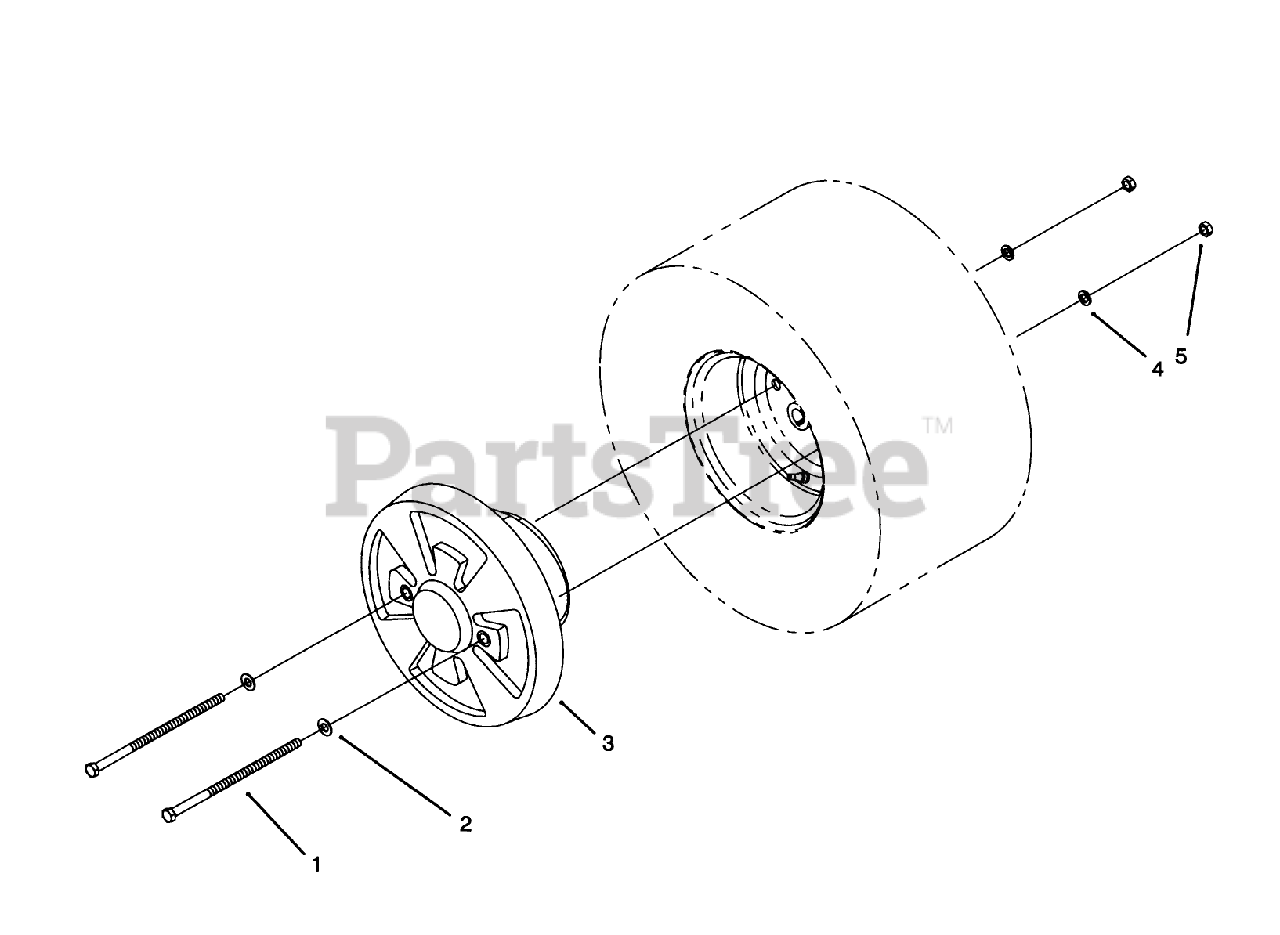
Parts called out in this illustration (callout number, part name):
1	SCREW-HH
2	WASHER-FLAT
3	WHEEL WEIGHT
4	WASHER-LOCK
5	NUT-HEX
